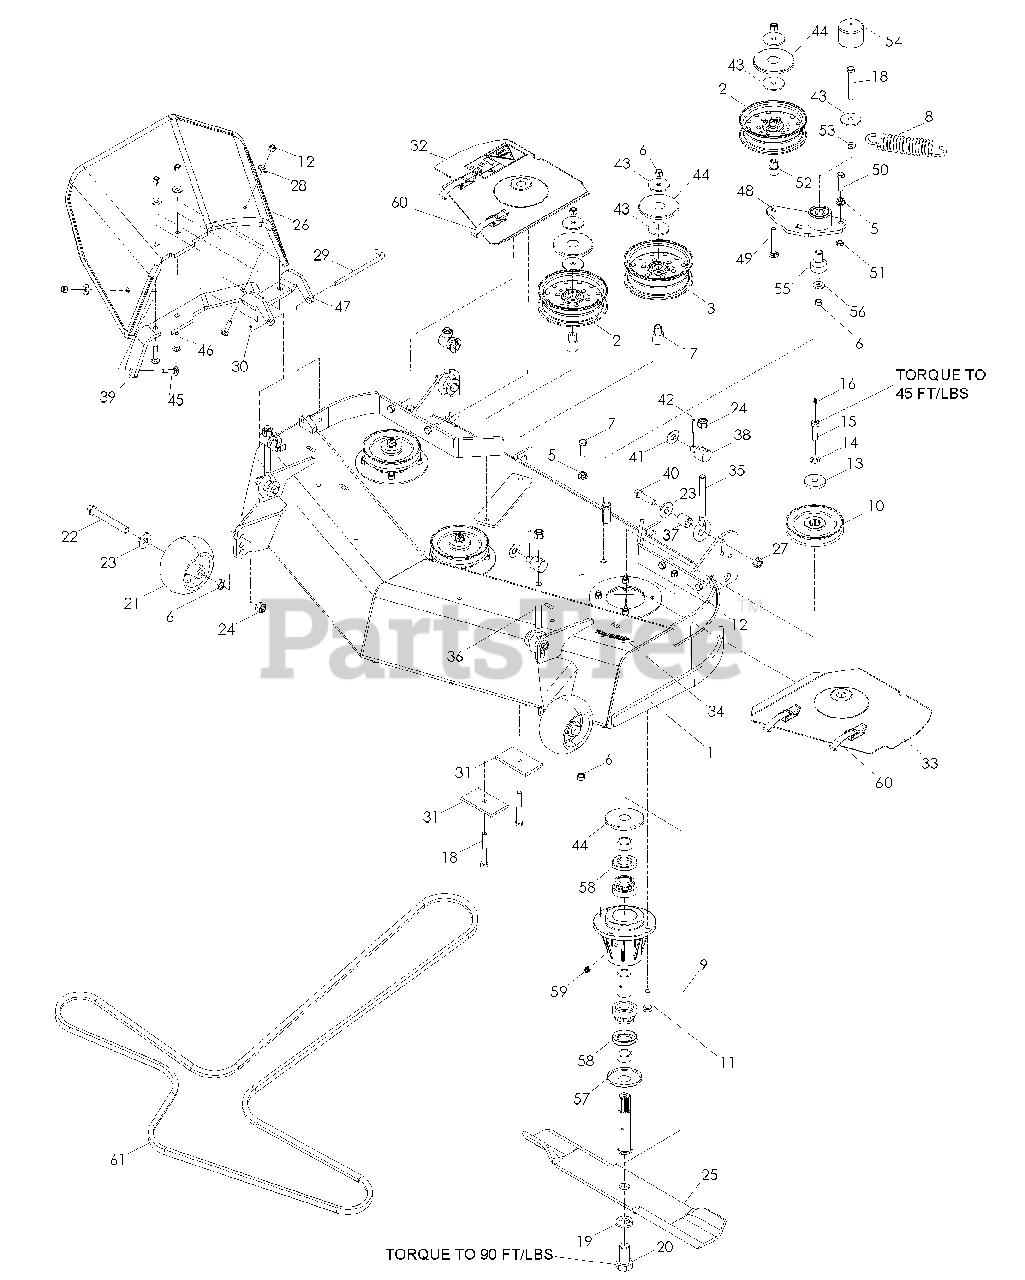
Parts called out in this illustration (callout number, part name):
1	DECK w/DECALS
2	PULLEY, IDLER
3	PULLEY, IDLER
4	NUT 1/2-13
5	NUT 3/8-16 WHIZLK
6	NUT 3/8-16 HEX NYLOC
7	HCS 3/8-16 x 1 1/4
8	SPRING, EXTENSION
9	SPINDLE ASSEMBLY
11	HCS 5/16-18 x 1 1/4
12	NUT 5/16-18 HEX NYLOC
13	WASHER, HEAVY
14	LOCKWASHER 7/16
15	HCS 7/16-20 x 1 1/2 GR8
16	ZERK, STRAIGHT 1/4-28
17	BUSHING, IDLER
18	HCS 3/8-16 x 3
19	WASHER 5/8 SPLIT LOCK
20	HCS 5/8-18 x 1 1/4
21	WHEEL, GAUGE
22	HHB 1/2-13 x 4
23	WASHER 1/2 SPRING
24	NUT 1/2 -13 HEX NYLOC
25	BLADE 14 5/8
26	CHUTE, DISCHARGE
27	NUT 7/16-14 HEX CTRLK GR A
28	WASHER 5/16 STD FLT
29	PIN, CLEVIS
30	PIN, COTTER 1/8 x 3/4
31	PAD
32	BELT SHIELD w/DECALS, RT
33	BELT SHIELD w/DECALS, LT
34	DECAL, TUNNEL
36	EYE BOLT 1/2-13
39	REINFORCEMENT, BRKT
40	HCS 7/16-14 x 1 3/4
41	WASHER 9/16 STD FLT
42	PIN, COTTER 1/8 x 1
43	WASHER 3/8 SPECIAL
44	DUST CAP, TOP
45	RHSNB 5/16-18 x 1 1/4
46	RHSNB 5/16-18 x 1 1/2
47	BRACKET, CHUTE
48	ARM, IDLER w/BEARINGS
49	RHSNB 3/8-16 x 2 3/4
50	HCS 3/8-16 x 1 1/2 GR8
51	NUT 3/8-16 HEX JAM
52	BUSHING, IDLER
53	WASHER 3/8 SAE FLT
54	CAP, VINYL
55	BEARING, PIVOT
56	WASHER 3/8 FLAT STD
57	DUST CAP, BOTTOM
58	SEAL, SHAFT
59	GREASE POPPET
60	DRAW LATCH
61	BELT, DECK
